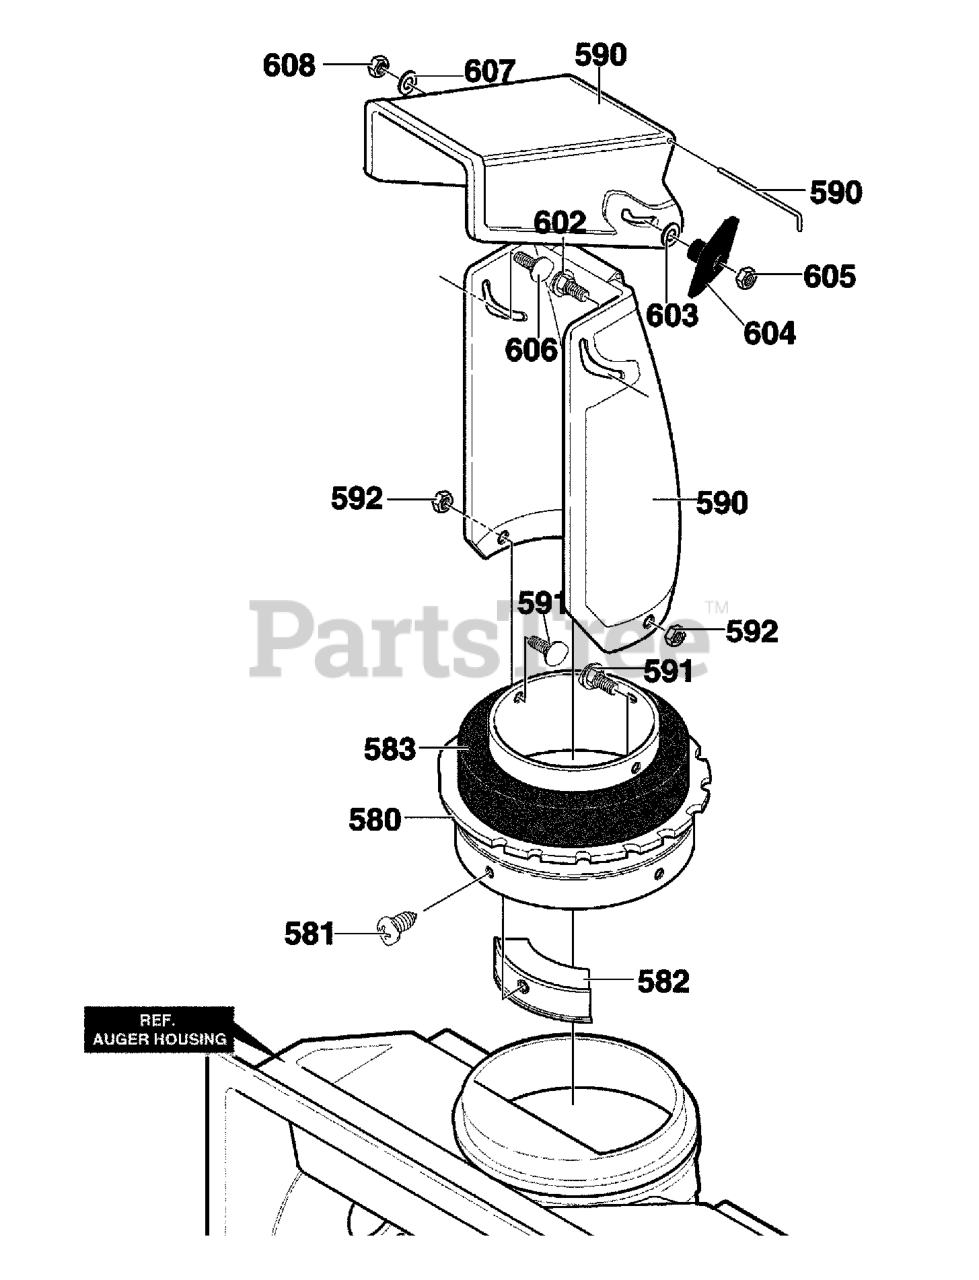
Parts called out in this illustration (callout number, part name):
580	RING, CHUTE
581	SCREW, #10X.50
582	GUIDE, CHUTE
583	DONUT FOAM
590	CHUTE ASSY.
591	SCREW 1/4-20X.50
592	NUT, CNTRLK 1/4-20
602	BOLT, 5/16-18X1.25 CARR.
603	WASHER, FLAT .349X.69X.066
604	KNOB, T
605	NUT, 5/16-18 REGHEX
606	SCREW, 5/16-18 x 0.75
607	WASHER, FLAT .349X.69X.066
608	NUT, 5/16-18 REGHEXCTRLK
